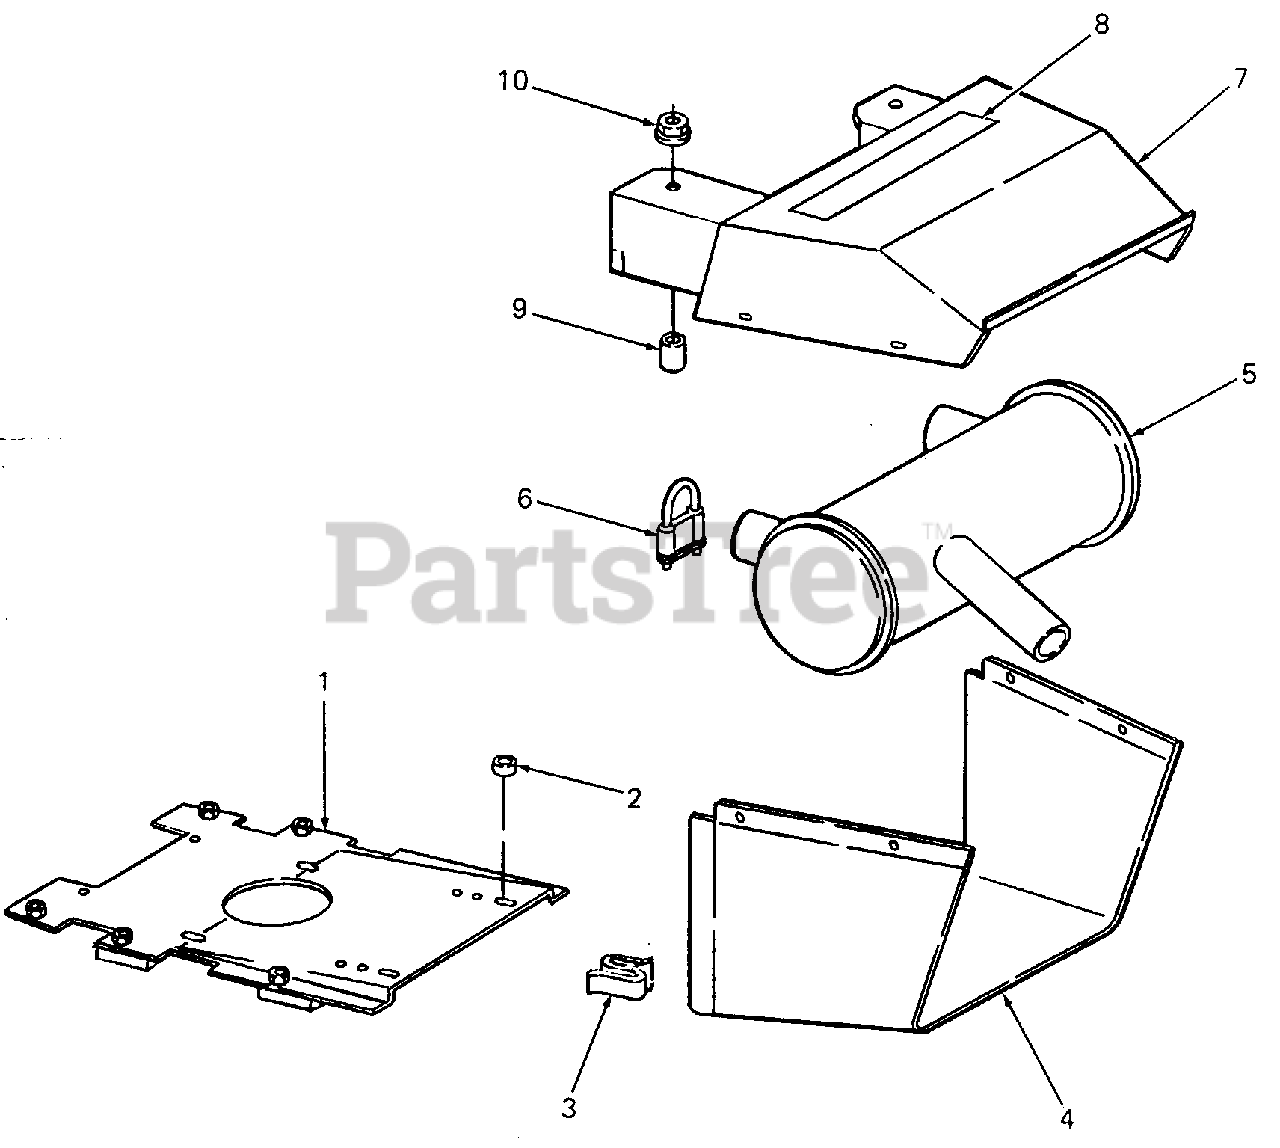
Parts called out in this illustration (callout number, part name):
1	Plate Assy, Engine Mounting
2	Spacer, .423 X .675 X .469 Lg
6	Clamp, Muffler
8	Label, Caution - Hot Surface
9	Spacer, .326 X .47 X .96 Lg
10	Nut, Hex Flange Lock, 5/16-18
